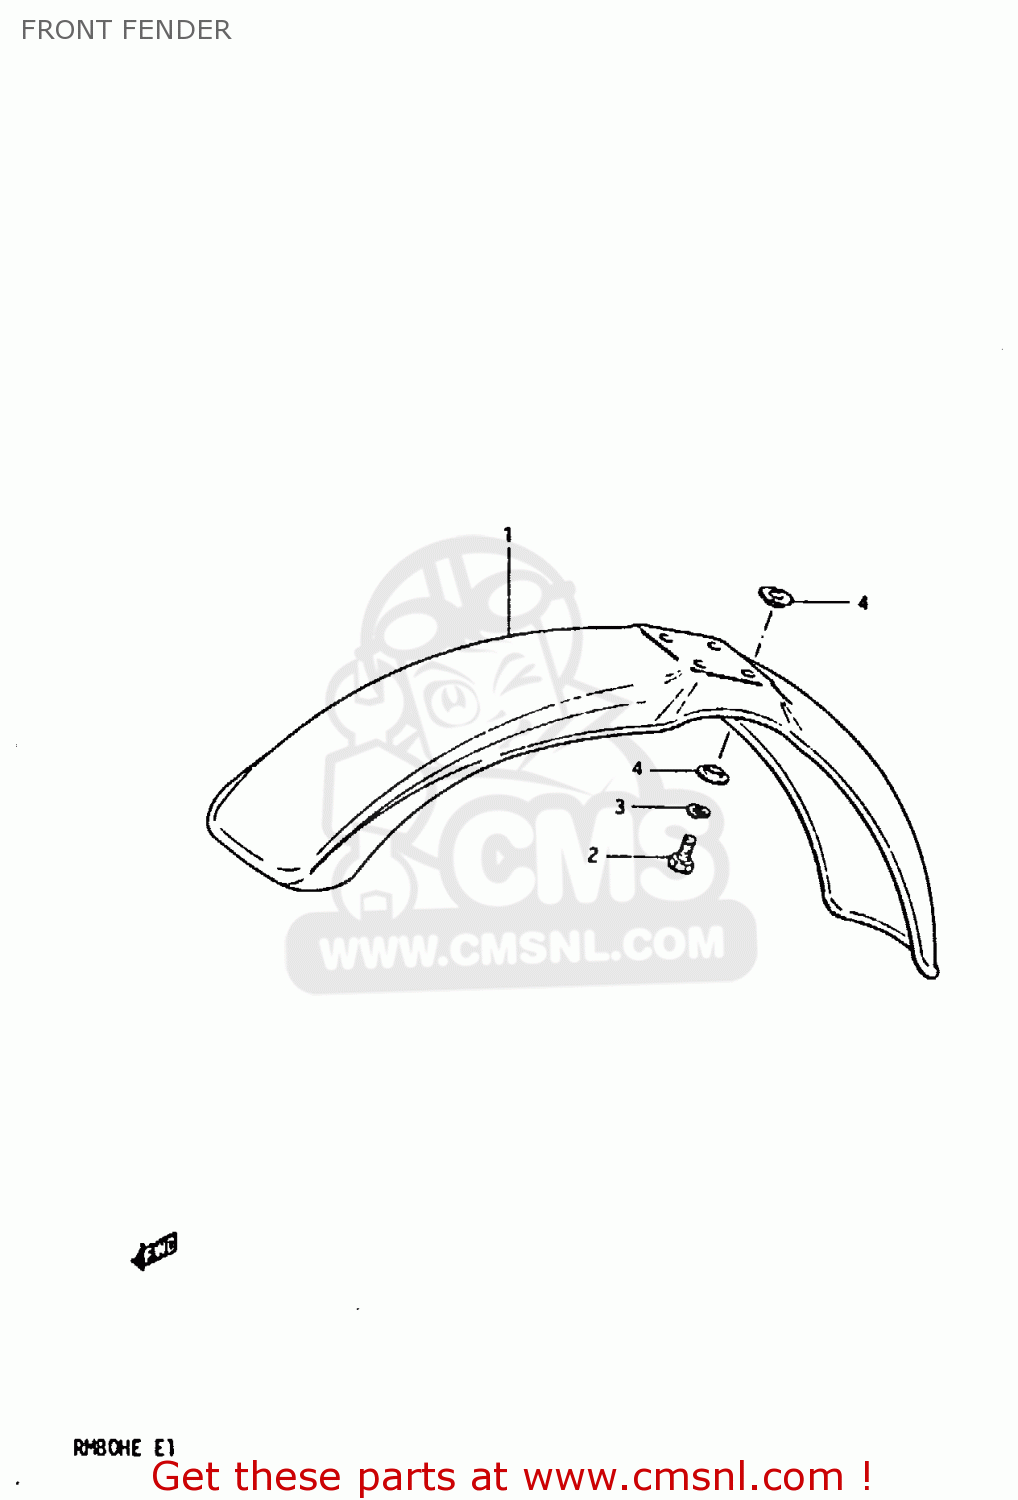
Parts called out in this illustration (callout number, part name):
1	FENDER,FR
2	BOLT, UPPER
3	LOCK WASHER
4	SPACER
